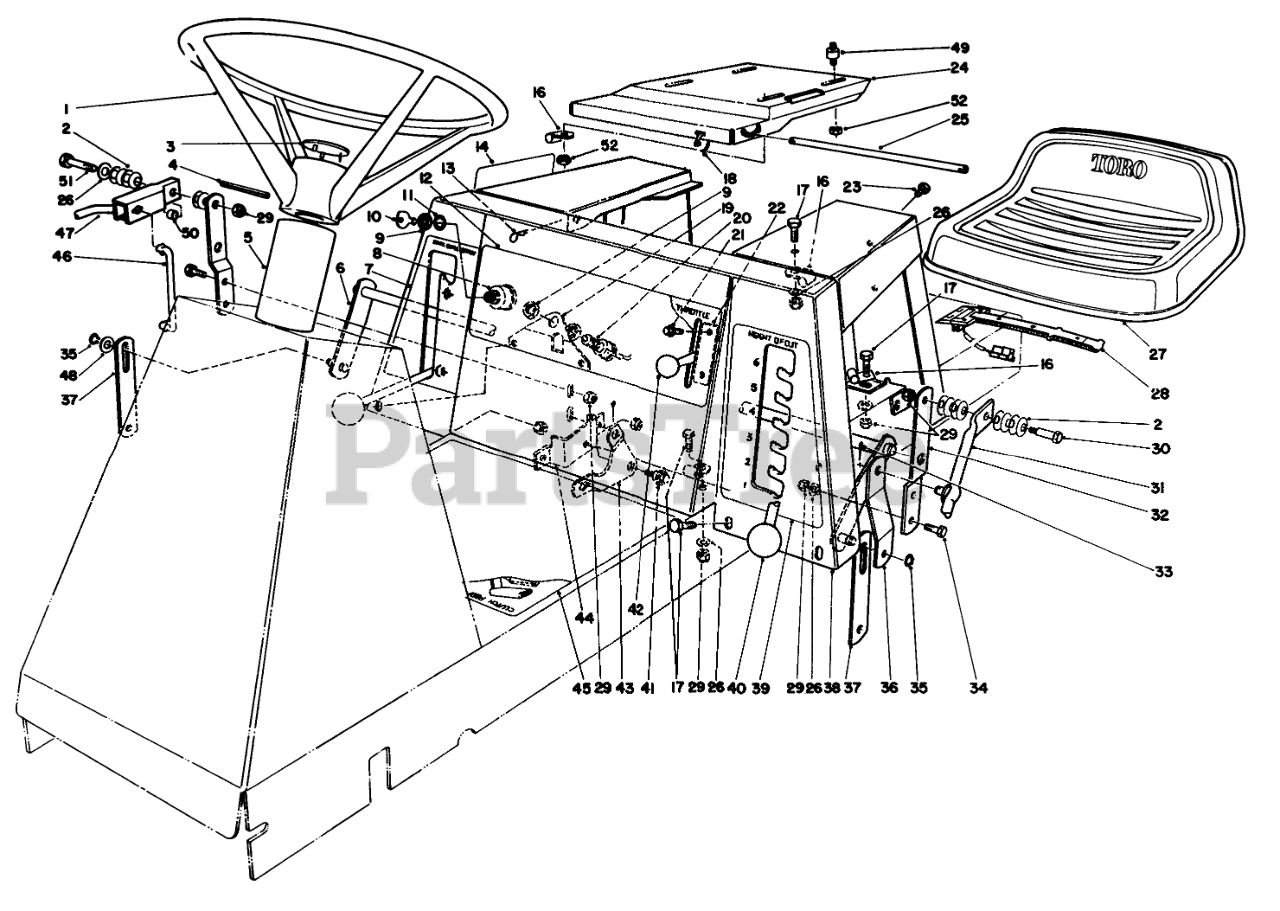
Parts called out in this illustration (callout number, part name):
1	Steering Wheel Assembly (Incl. Ref. #3)
2	WASHER-BELLEVILLE
3	Cap-Steering Wheel
4	PIN-ROLL
5	STRG. SHAFT COVER
6	Arm
7	DECK ENGAGE DECAL
8	Switch-Ignition (Incl. Ref. #9-11)
9	NUT-HH
10	Key
11	WASHER-TOOTH, INTERNAL
12	IGN & THROTTLE DECAL
13	PIN-COTTER
14	Decal Shift Pattern
16	CLAMP
17	SCREW-HH
18	TIE-CABLE
19	SWITCH MT BRKT
20	Switch-Deck (Incl. Ref. #8)
21	SCREW-HWHTF
22	Control-Throttle (Incl. Ref. #42)
23	SCREW-HH
24	SEAT BASE RO
25	SEAT BASE ROD
26	WASHER-PLAIN
27	Seat Assy. (Incl. Ref. #28)
28	SWITCH-SEAT
29	NUT-LOCK, NI
30	BOLT-SHOULDER
31	HOC LEVER WA B
32	Bracket
33	PIN-COTTER
34	SCREW-HH
35	RING-RETAINING
36	HOC ENGAGE BRKT R
37	DECK SUSP LINK B
38	Body-Seat
39	HOC DECAL
41	SCREW-SHOULDER
42	Knob
43	DECK ENGAGE BELLCRANK
44	BELLCRANK MTG BRKT
45	INSTRUCTION DECAL
46	BELLCRANK LINK(PLTD)
47	SHIFT LEVER WA B
48	WASHER-FLAT
49	ISOLATER-SEAT
50	SPACER
51	SCREW-HH
52	NUT-HF
